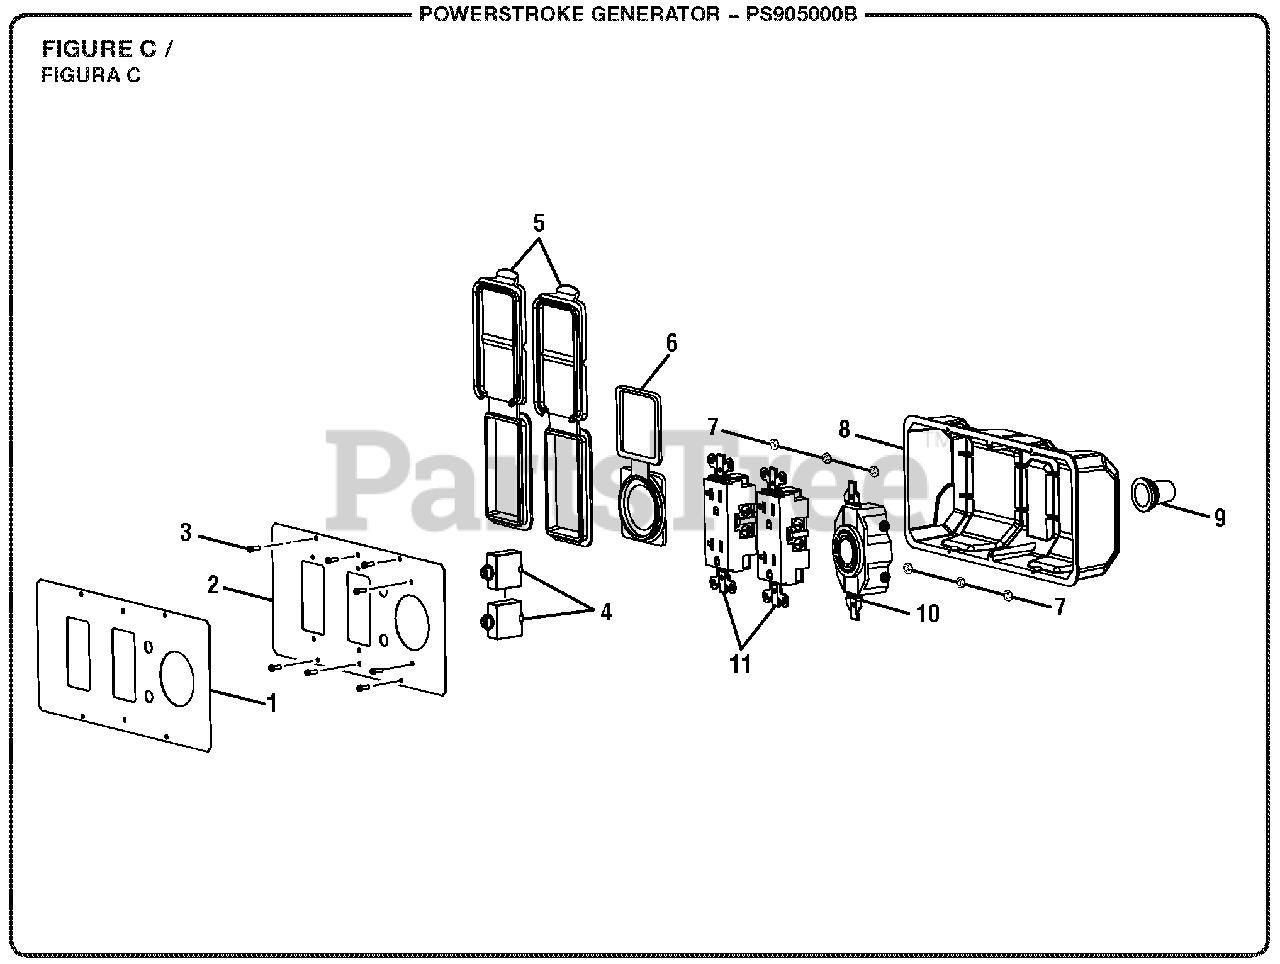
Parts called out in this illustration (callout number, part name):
1	Front Panel Label
2	Front Panel
3	Screw (#6-20 x .38 in.)
4	Circuit Breaker (20 Amp)
5	Outlet Cover (120 Volt)
6	Outlet Cover (240 Volt)
7	Lock Nut (#6- 32)
8	Control Box (Back Panel)
9	Rubber Sleeve
10	Twist Lock Receptacle (240 Volt)
11	Duplex Receptacle (120 Volt)
